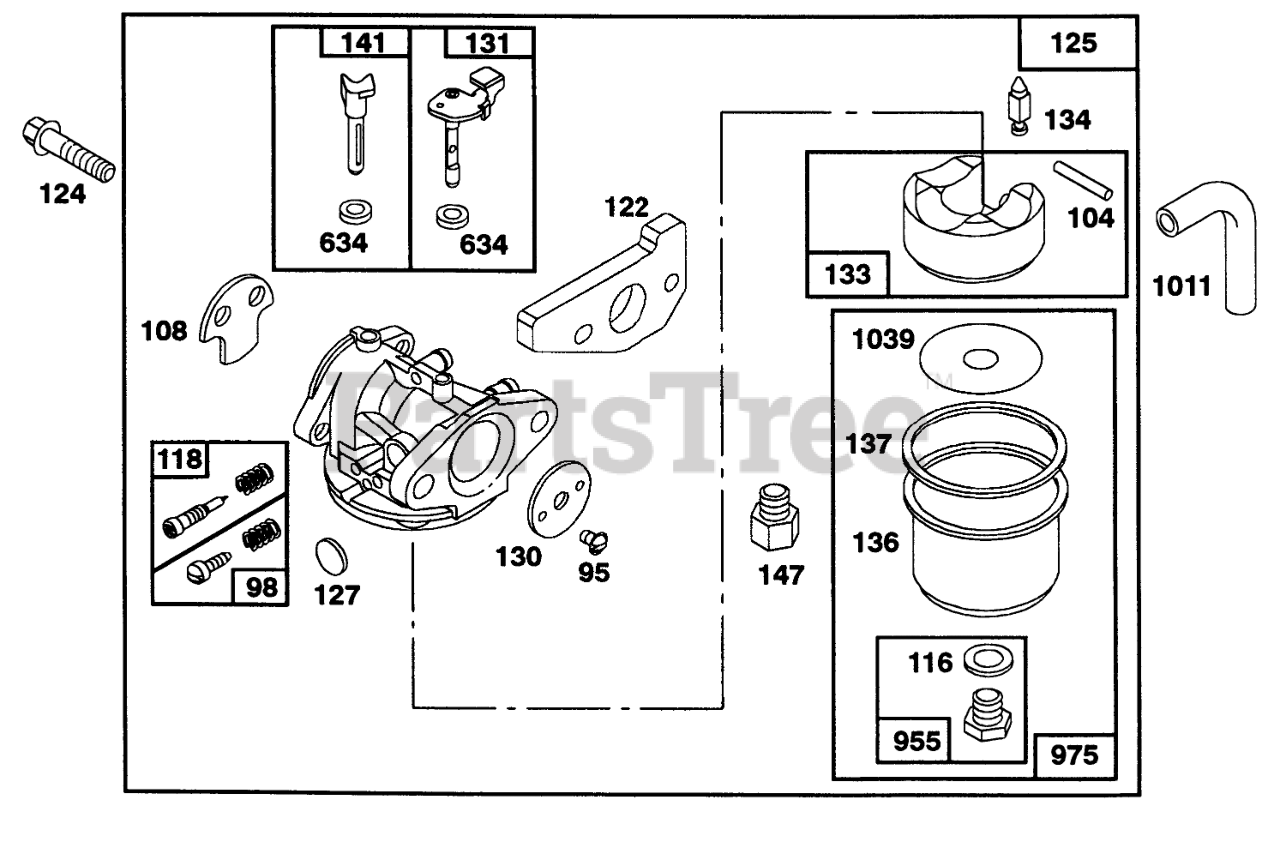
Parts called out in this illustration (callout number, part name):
95	SCREW - ROUND HEAD
98	IDLE ADJUSTING SCREW
104	FLOAT HINGE PIN
108	CHOKE VALVE
116	SEALING GASKET
118	VALVE KIT - NEEDLE
122	ADAPTER ASSEMBLY
124	HEX HEAD SCREW
125	CARBURETOR ASSEMBLY
127	PLUG
130	THROTTLE VALVE
131	THROTTLE SHAFT
133	FLOAT-CARBURETOR
134	Valve-Inlet (Includes Seat)
136	FLOAT BOWL
137	FLOAT BOWL GASKET
141	CHOKE SHAFT
147	JET ADAPTER
634	SEAL WASHER
955	HEX HEAD SCREW
975	CARBURETOR BOWL ASM
1011	VENT TUBE
1039	FLOAT LIMITER
